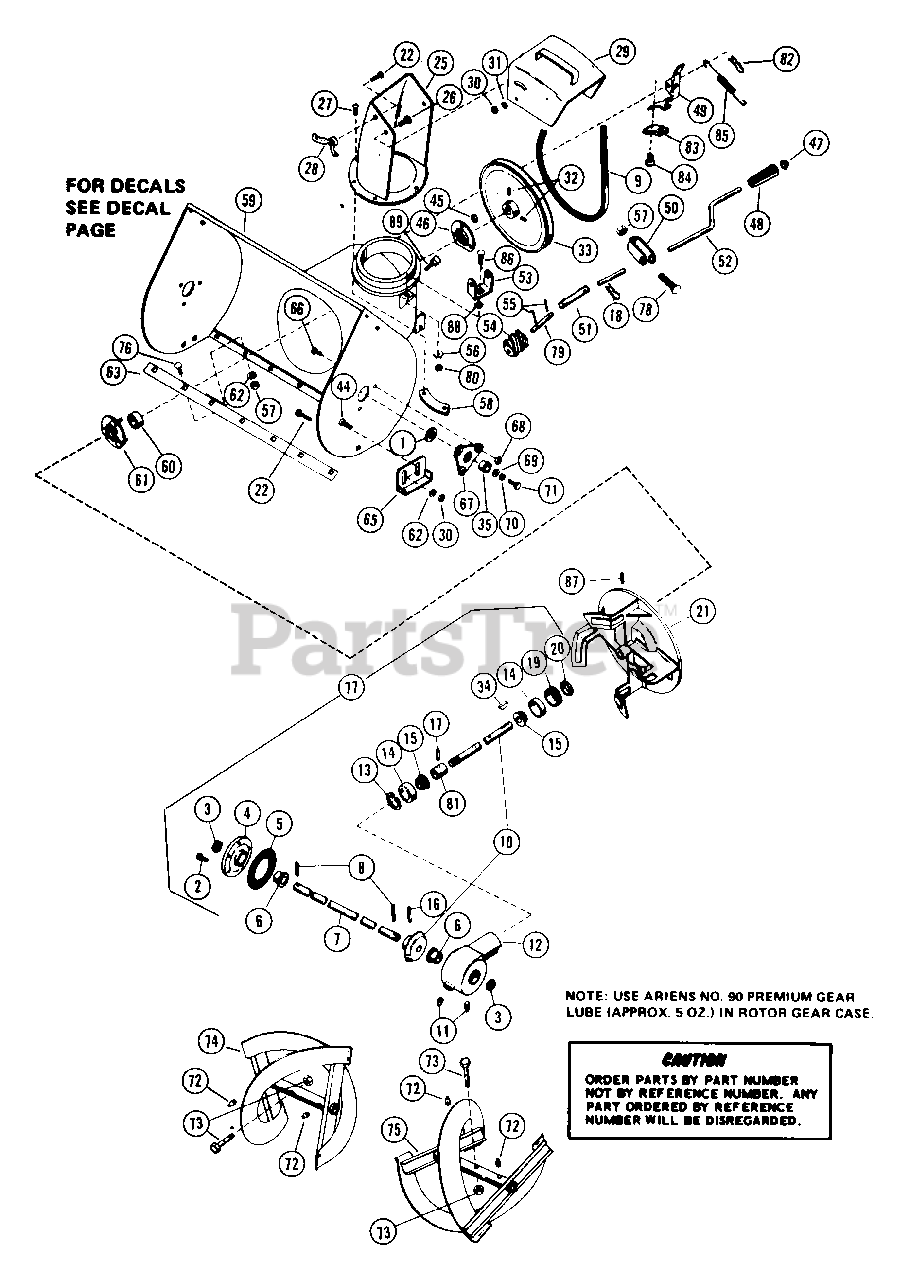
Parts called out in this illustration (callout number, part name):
1	WSHR-FL-STL 1.010X1.505X.062PL
2	BLT-SERHFWH .25-20X.75 PL
3	SEAL 1.000X1.312X.150
4	GEAR CASE FLANGE
6	BSHG-FLG 1.000X1.12X.62X1.50BR
7	FRONT GEAR SHAFT
8	PIN-ROLL .188X1.50
10	PINION & SHAFT SERVICE ASSEMBL
11	PIPE PLUG
12	CASE, GEAR - C.I.
13	RG-RTNG INT 1.781 HSG X.062
14	BRG-CUP 1.781X.475
15	BRG-CONE .750X.61
16	PIN-ROLL .313X1.38
17	PIN-ROLL .250X1.25
18	PIN-HAIR INT .09X.188 PL
19	ADJUSTMENT PLUG
20	SEAL .750X1.499X.225
21	FAN - 12"
22	BLT-RDHDSQNK .38-16X.75 SHT PL
25	CHUTE - DISCHARGE
26	BLT-HEX .38-16X.75 PL GR2
27	SCR-TAP 10-24X.375 CRPH 1A
28	WING NUT
29	SERVICE DEFLECTOR ASSM
30	NUT-LK-CTR .375-16 GR A PL
31	WSHR-LK .375X.115 HVY PL
32	SCR-SET .32-18X.38 SKHCUPNL OH
33	PLY-? 9.0X.75
34	KEY-WDRF .188X.875X.375 SAE11
35	BSHG-FLG 1.000X1.12X.62X1.50BR
44	BLT-RDHDSQSHNK .38-16X1.00 PL
45	NUT-LK-CTR .250-20 PL
46	BEARING FLANGE
47	CAP, 3/8 ROD YWZC
49	BRAKE ARM ASSEMBLY
50	BRACKET
51	SLEEVE CONNECTOR
52	CHUTE CONTROL CRANK
53	WORM CLEVIS
54	WORM GEAR
55	PIN-ROLL .125X.75
56	WSHR-LK .313X.062
57	NUT-LK .312-18 GR A PL
58	CHUTE CLAMP
59	24 IN BLOWER HOUSING ASSY
60	BRG-BALL .750X1.750X.50
61	BEARING FLANGE
62	WSHR-FL-STL .38X.875X.083 PL
63	SCRAPER BLADE 24"
65	RUNNER
66	SCR-SLTR-SERNK .25-20X.62 PL
67	BEARING SUPPORT
68	NUT-LK-FLG .250-20 PL
69	WSHR-FL-STL .511X1.441X.125 PL
70	WSHR-LK .500X.151 HVY PL
71	BLT-HEX .50-13X1.00 PL GR2
72	SPIN DRIVE ZERK FITTING
73	SHEAR BOLT SERVICE ASSEMBLY
74	RAKE, RIGHT-24"(1ID X 15.88OD)
75	RAKE, LEFT-24"(1"ID X 15.88OD)
76	BLT-RDHDSQNK .312-18X.62 PL
77	GEAR CASE - CAST IRON
78	RVT .203 X .437 RH ST
79	WORM SHAFT
80	NUT-HEX .312-18
81	BEARING SPACER
82	PIN-COTR .12X1.0 PL
83	BRAKE LINING
84	RVT-TBLR .187X.375 OH ST PL
85	SG-TENS .062X.56X8.0 WLD 11
86	BLT-RDHDSQNK .31-18X.75 GR5 PL
87	PIN-ROLL .250X1.75
88	WSHR-LK-EXT .313X.030 PL
89	BLT-SCRHFWH .38-16X.75 PL
